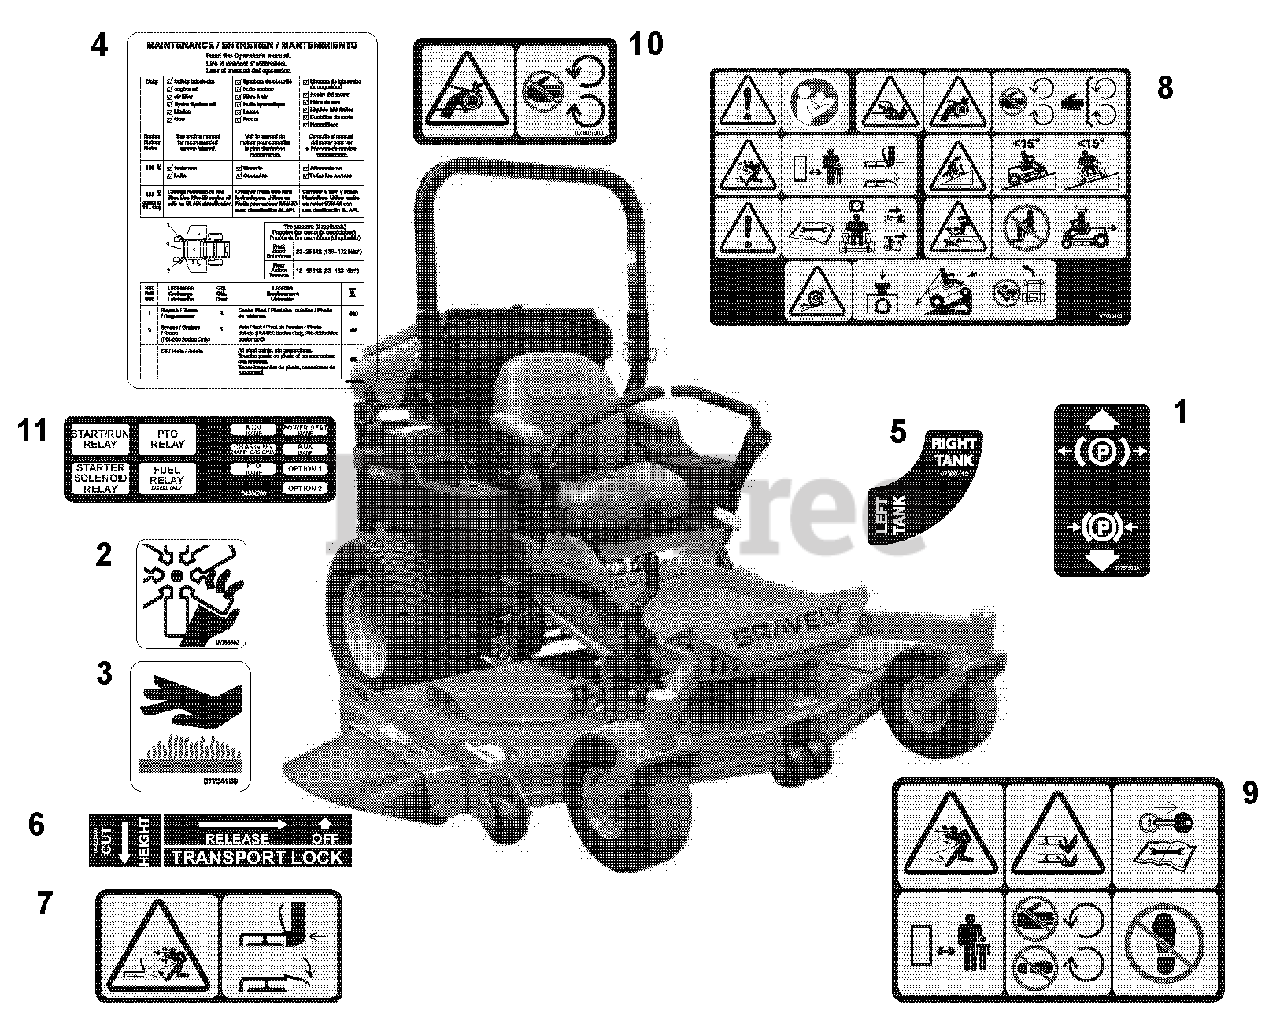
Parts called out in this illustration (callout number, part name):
1	Decal, Parking Brake Lever
2	Decal, Danger Fan
3	Decal, Hot Surface
4	Decal, Maintenance Instructions
5	Decal, Diesel Fuel Valve
6	Decal, Transport Lock
7	Decal, Deck Guarding Safety
8	Decal, Instruction
9	Decal, Mower Deck Safety
10	Decal, Safety Guarding
11	Decal, Fuse Box Layout
